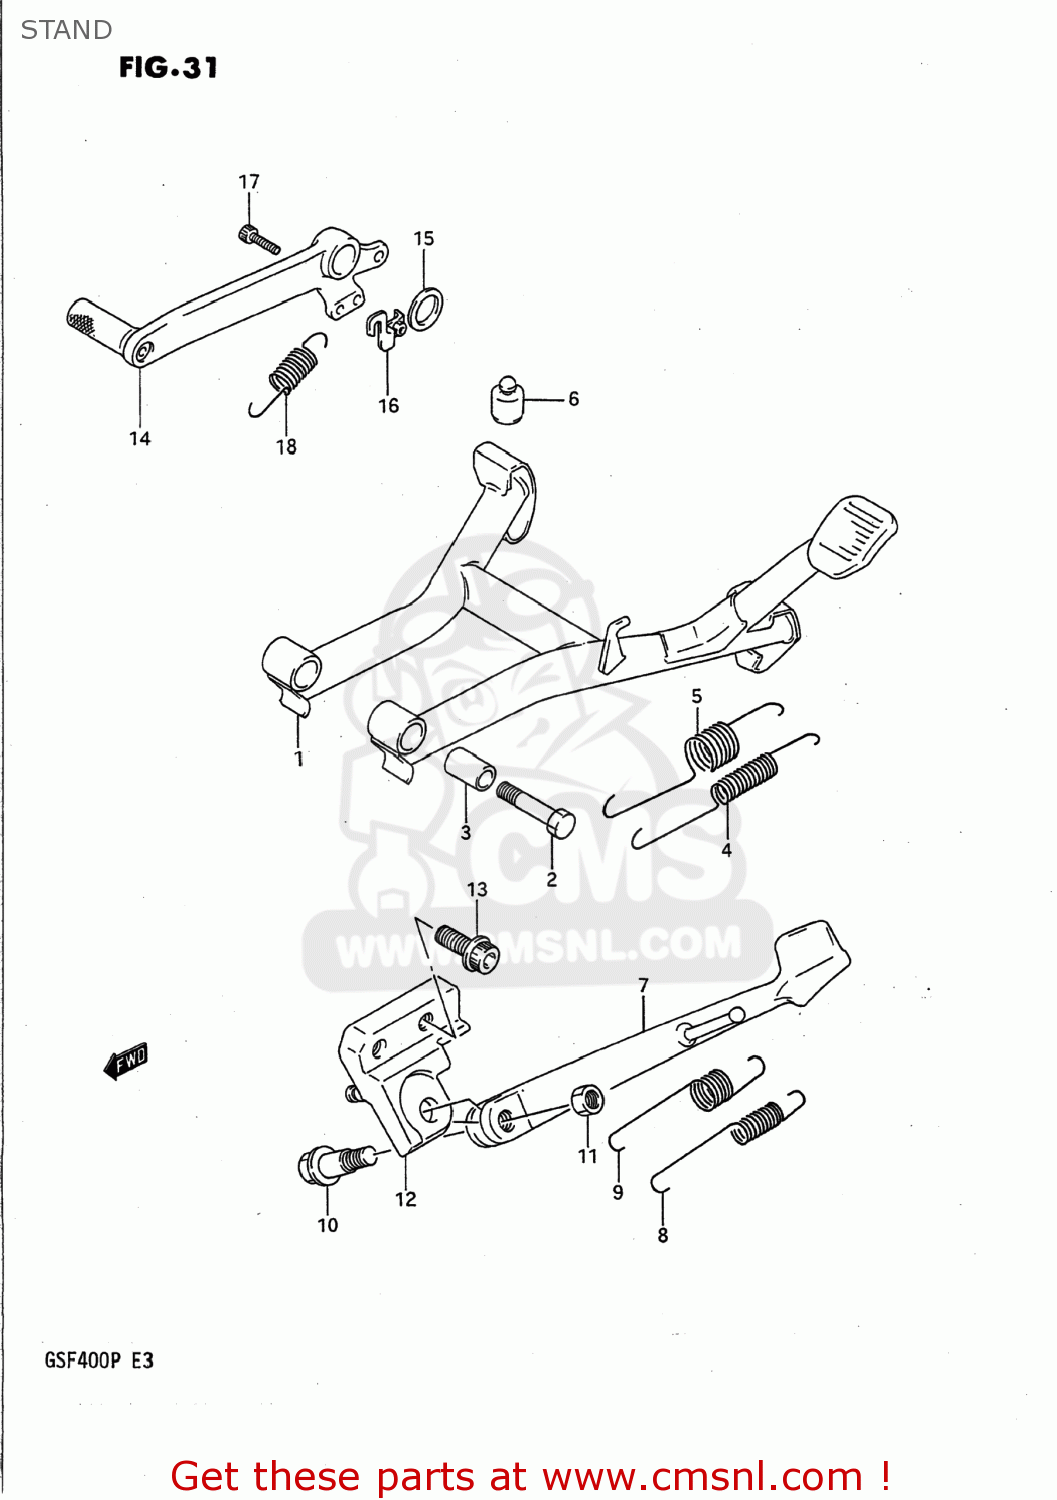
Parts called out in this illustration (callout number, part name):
1	STAND,CENTER
2	BOLT(10X43)
3	SPACER(10X16X25.5)
4	SPRING
5	SPRING OUTER
6	CUSHION
7	STAND,SIDE
8	SPRING
9	SPRING
10	BOLT(10X30)
11	NUT
12	BRACKET,SIDE STAND
13	BOLT
14	PEDAL,BRAKE
15	WASHER(18.2X27X1)
16	BRACKET,STOP LAMP SWITCH SPR
17	BOLT
18	SPRING
